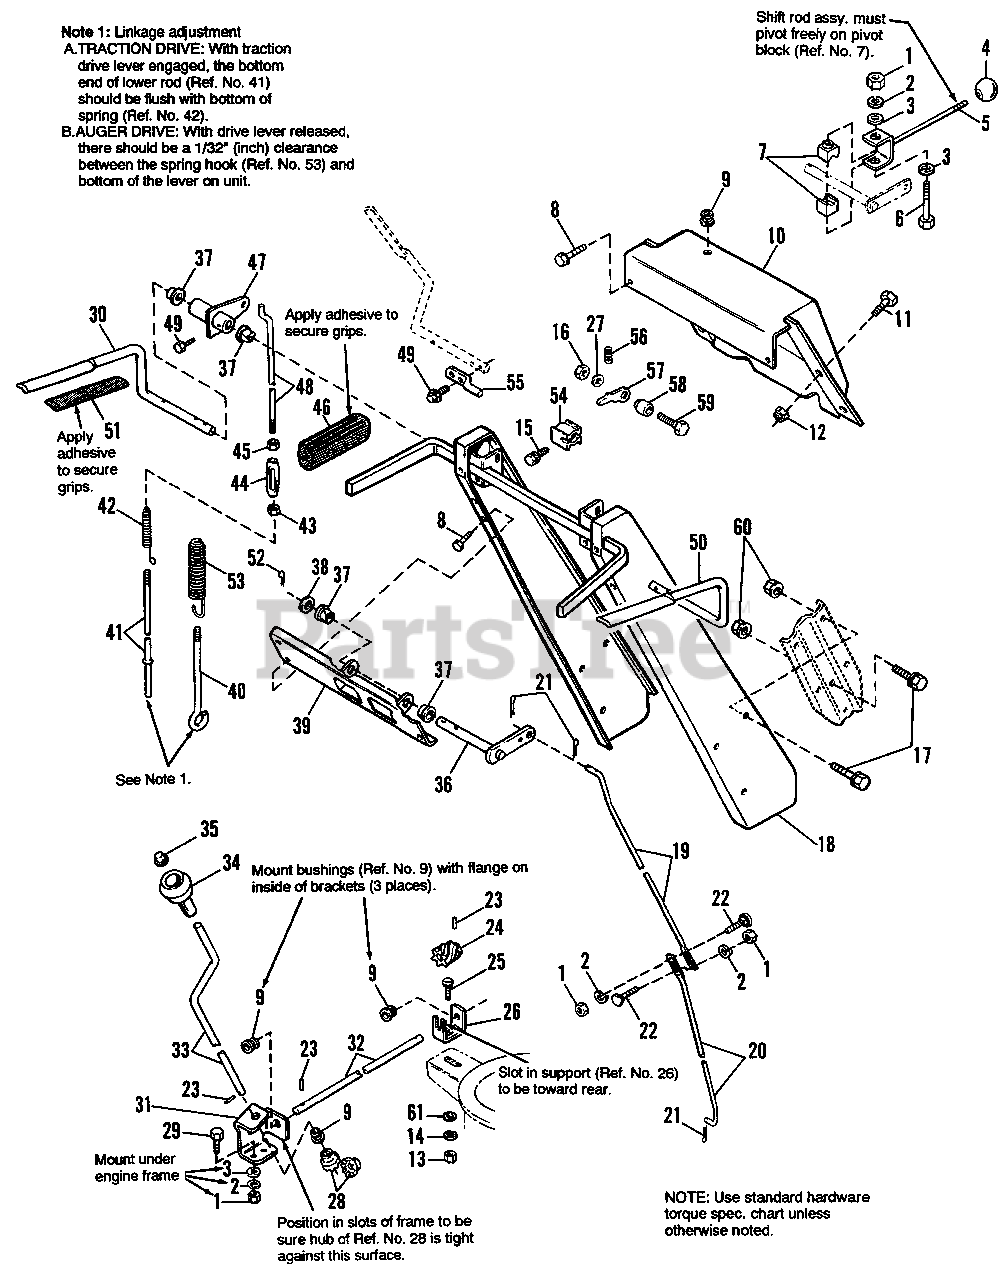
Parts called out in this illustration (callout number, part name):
1	NUT, Hex, 1/4-20
2	LOCKWASHER, 1/4
3	WASHER, Flat, 9/32
5	SHIFT ROD ASSY.
6	CAPSCREW, Hex Hd., 1/4-20 x 2-1/4
7	BLOCK, Pivot
8	SCREW, Taptite, 1/4-20 x 1/2
9	BUSHING, Plastic
10	DASH, Handle
11	CAPSCREW, Washer Hd., 1/4-20 x 3/4
12	NUT, Nylon Lock, 1/4-20
13	NUT, Hex, 5/16-18
14	LOCKWASHER, 5/16
15	SCREW, Taptite, #10-24 x 1
16	NUT, Hex Lock, 5/16-18
17	CAPSCREW, Whizlock 5/16-18 x 3/4
18	HANDLE ASSY.
19	ROD, Shift, Upper
20	ROD, Shift, Lower
21	PIN Cotter
22	BOLT, Carriage, 1/4-20 x 3/4
23	PIN, Roll, 1/8 x 3/4
24	WORM, Chute
25	BOLT, Carriage, 5/16-18 x 3/4
26	SUPPORT, Worm
27	WASHER, Flat, 13/32
28	GEAR, Universal
29	CAPSCREW, Hex Hd., 1/4-20 x 3/4
30	HANDLE, Clutch, L.H.
31	SUPPORT, Universal Gear
32	ROD, Chute Worm
33	ROD, Chute Control
34	KNOB, Spinner
35	PALNUT
36	PIVOT ROD ASSY.
37	BUSHING, Plastic
38	WASHER
39	BRACKET, Shift Control
40	ROD, Clutch-Lower, Auger
41	ROD, Clutch-Lower, Traction
43	NUT, Hex, #10-24, R.H.
45	NUT, Hex, #10-24, L.H.
46	GRIP, Handle Bar
47	CLUTCH LEVER ASSY.
48	ROD, Clutch-Upper
49	SCREW, Taptite, 1-24 x 1
50	HANDLE, Clutch R.H.
51	GRIP, Clutch
52	PIN, Cotter, 1/8 x 1
53	SPRING, Extension
54	GUIDE, Control
55	ROD, Control
56	SPRING
57	LATCH, Control
58	SPACER, Special
59	CAPSCREW, Hex Hd., 5/16-18 x 1-1/2
60	NUT, Hex, Flange Whizlock 5/8-18
61	WASHER, Plain 11/32
